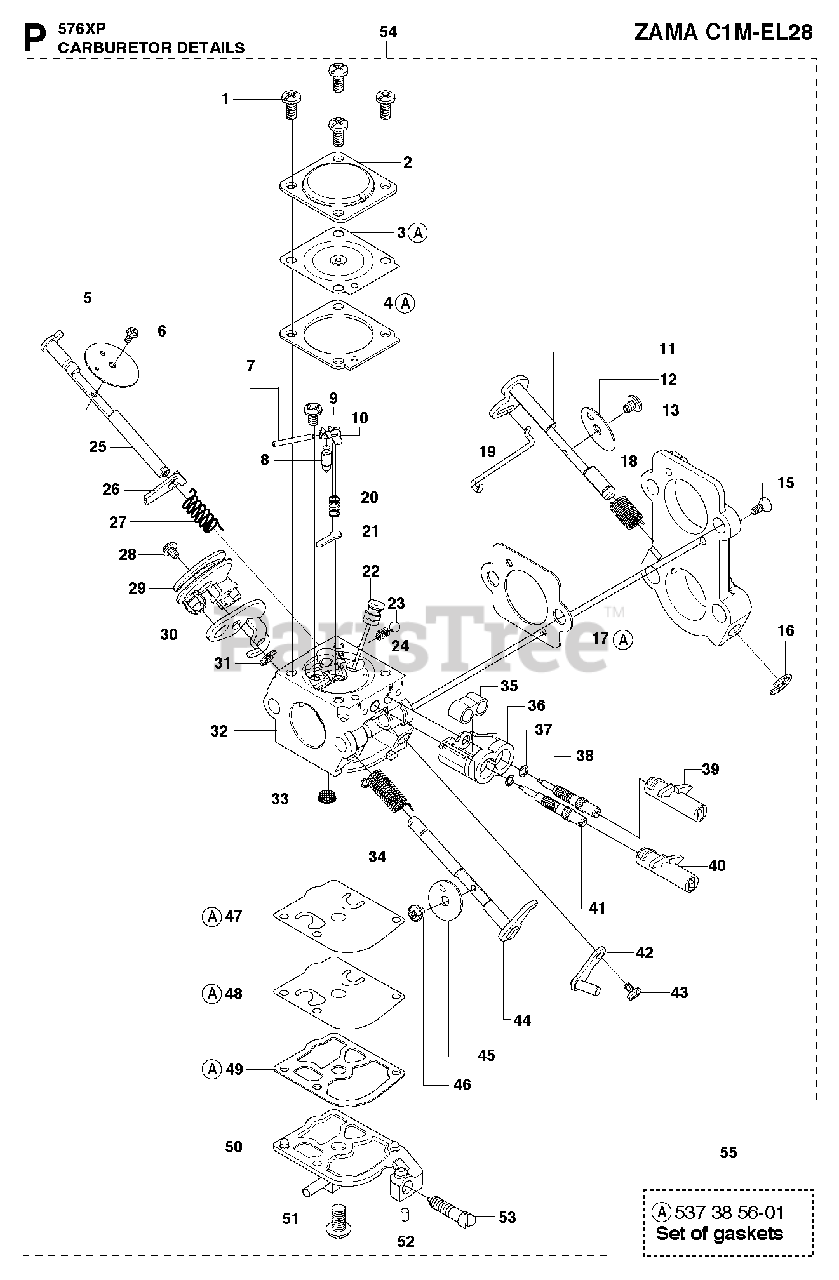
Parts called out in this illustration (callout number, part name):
1	SCREW
2	COVER
3	DIAPHRAGM
4	GASKET
5	SCREW
6	CHOKE FLAP
7	PIN FULCRUM
8	INLET NEEDLE
9	SCREW
10	LEVER
11	SHAFT
12	THROTTLE FLAP
13	SCREW
15	SCREW
16	CLIP
17	GASKET
18	SPRING
19	ROD
20	SPRING
21	PLUG
22	JET
23	BALL
24	SPRING
25	CHOKE SHAFT
26	LEVER
27	SPRING
28	SCREW
29	LEVER
30	LEVER
31	CLIP
32	RP CARBURETOR
33	STRAINER
34	SPRING
35	SLEEVE
36	SLEEVE
37	WASHER
38	NEEDLE HIGH SPEED
39	LIMITER
40	LIMITER
41	LOW SPEED NEEDLE
42	LEVER
43	SCREW
44	THROTTLE SHAFT
45	FLAP
46	SCREW
47	PUMP DIAPHRAGM
48	DIAPHRAGM
49	GASKET
50	COVER
51	SCREW
52	PLUG
53	SCREW
54	RP CARBURETOR
55	GASKET SET
